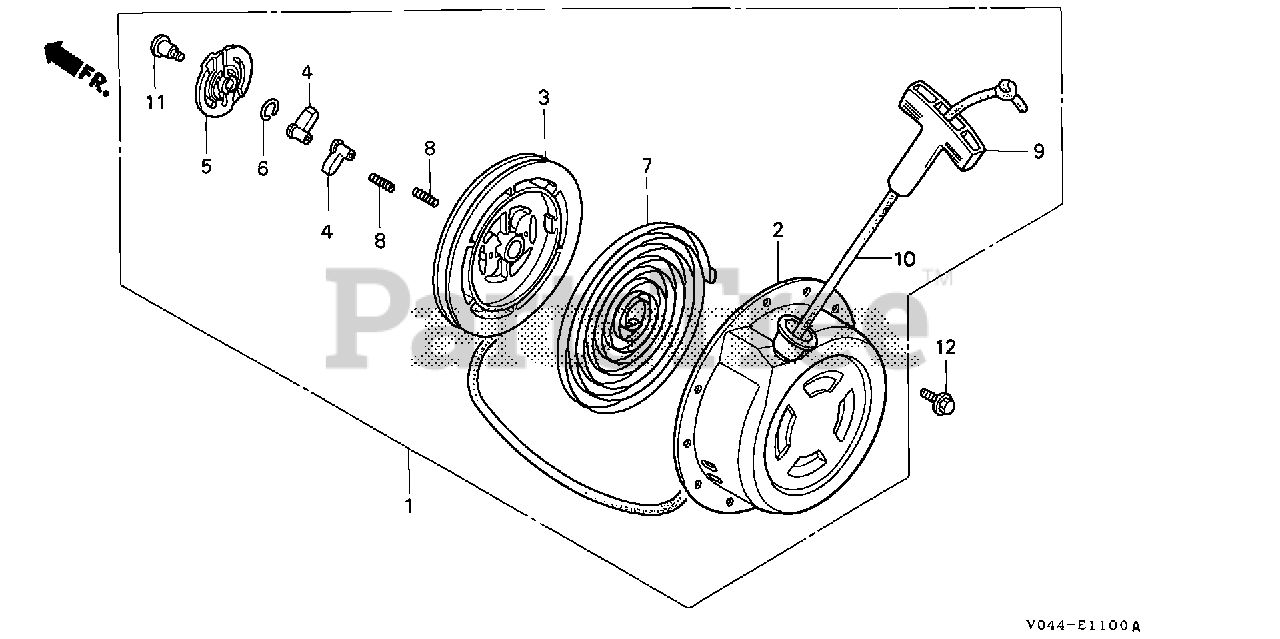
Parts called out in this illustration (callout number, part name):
1	STARTER ASSY., RECOIL *R280* (POWER RED)
2	CASE, STARTER *R280* (POWER RED)
3	REEL, RECOIL STARTER
4	RATCHET, STARTER
5	GUIDE, RATCHET
6	SPRING, FRICTION (ENGINE NO.)
7	SPRING, RECOIL STARTER
8	SPRING, RETURN (ENGINE NO.)
9	GRIP, STARTER
10	ROPE, RECOIL STARTER (#5X55") (NA USE ALT:08550-ZG921-11)
11	SCREW, SETTING (ENGINE NO.)
12	BOLT, FLANGE (6X10)
